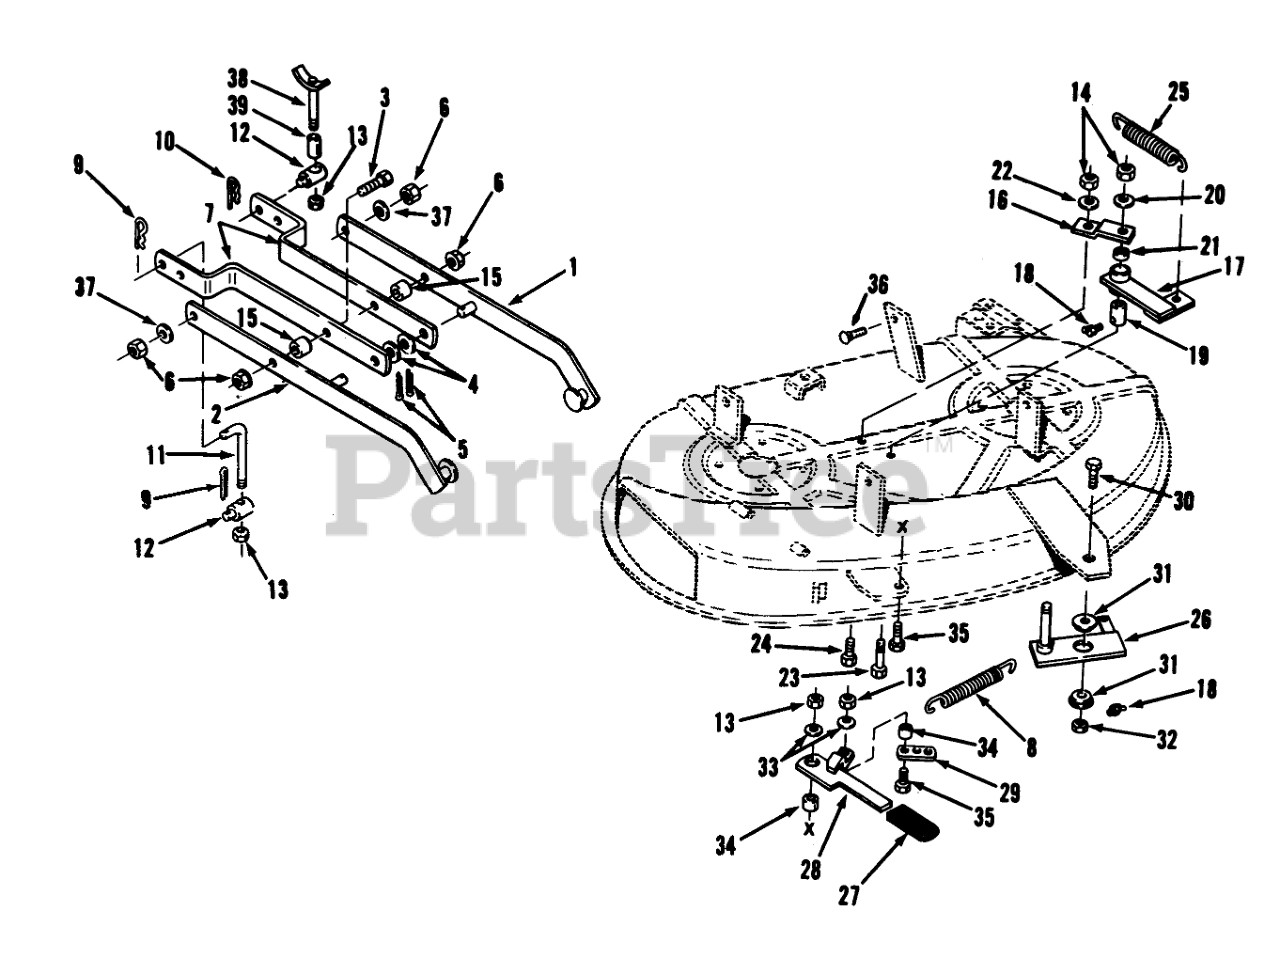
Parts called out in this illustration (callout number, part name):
1	Draft Bar LH
2	Draft Bar RH
3	Bolt
4	WASHER
5	PIN-4
6	LOCKNUT-FLANGE
7	Bar-Leveler
8	Spring
9	Cotter Pin
10	Hairpin
11	ROD-LIFT
12	Trunion
13	NUT
14	Nut
15	SPACER
16	Strap
17	Arm-Idler
18	Fitting-Grease
19	SPACER-2.0 LG R
20	Washer
21	BUSHING
22	WASHER 5/16 SAE
23	Pin-Cotter
24	Bolt
25	Spring
26	Countershaft
28	Lever
29	Link
30	Bolt
31	BUSHING
32	Nut
33	WASHER
34	SPACER
35	Bolt
36	Bolt
37	SPACER
38	WLDMT-HANGER ROD
39	SPACER .375 ID X 1.6
